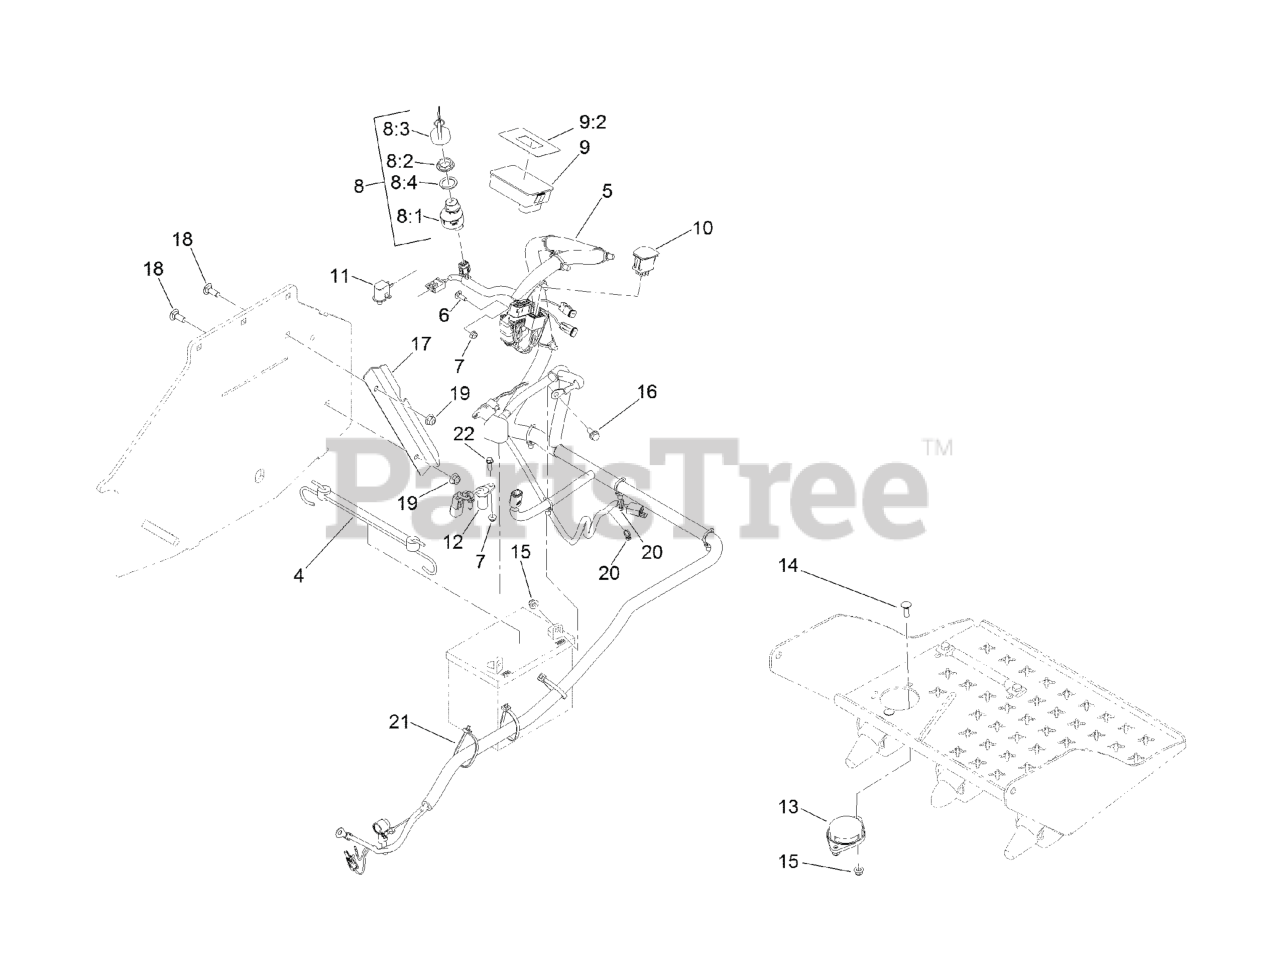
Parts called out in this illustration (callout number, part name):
4	HOLDDOWN-BATTERY
5	HARNESS-WIRE
6	BOLT-CARR
8	IGNITION SWITCH ASM
8:1	Switch-Ignition
8:2	NUT-MOUNTING
8:3	IGNITION KEY SET
8:4	WASHER-BACKUP
9	Hour Meter ASM
9:2	DECAL-METER, HOUR
11	SWITCH-BAIL
12	SENSOR-QUADRATURE
13	SWITCH-SEAT
14	BOLT-CARR
15	NUT-HF, NI
16	SCREW-HHF
17	GUARD-HARNESS
18	BOLT-CARR
19	NUT-HF, NI
20	TIE-CABLE
21	TIE-PLASTIC
22	SCREW-HWH
